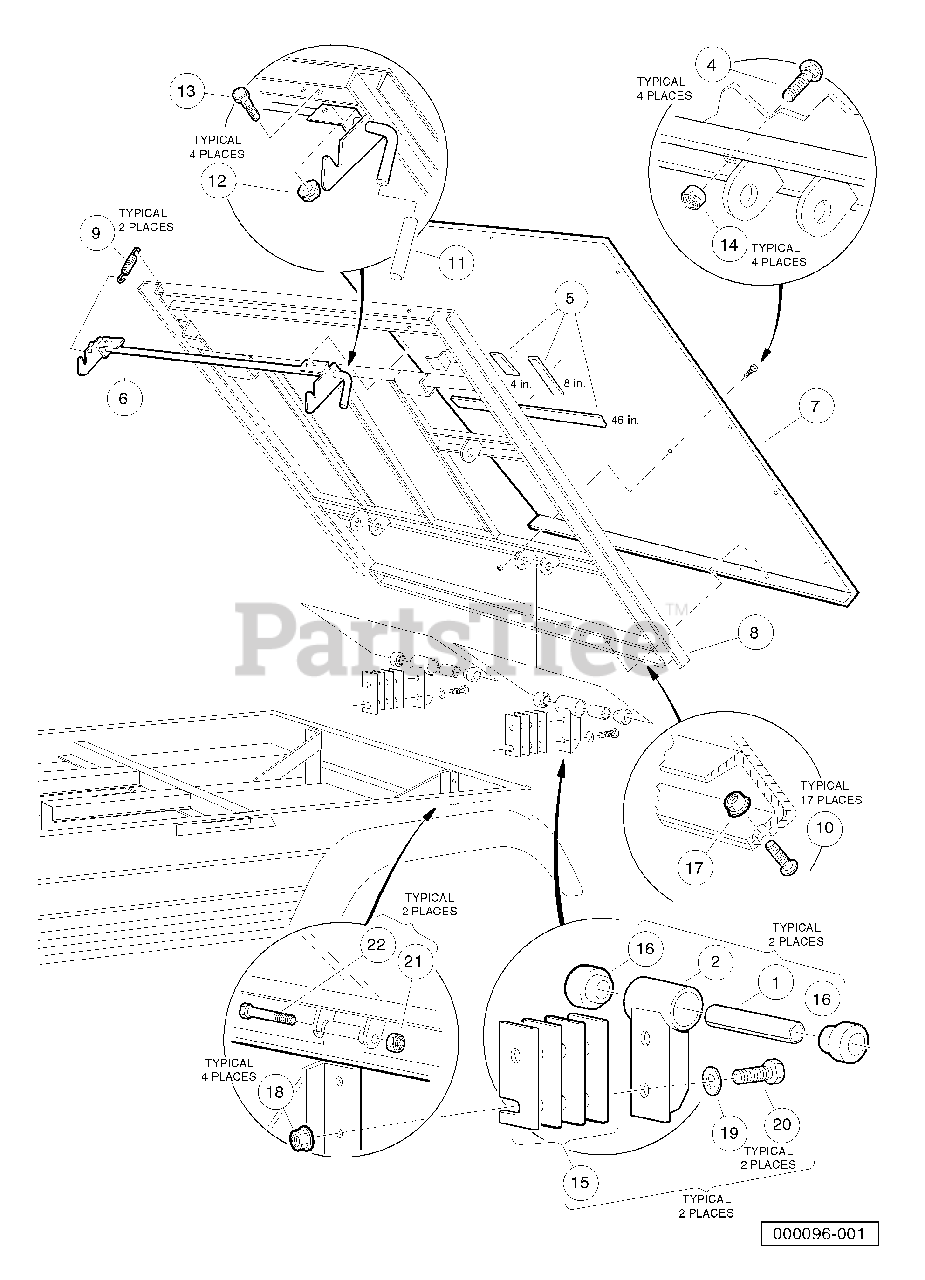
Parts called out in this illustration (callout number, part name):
1	Bushing, Steel
3	Assembly, Tilt Bed
4	Bolt, Carriage, 5/16-18 X 1.00
5	Tape, Vinyl Foam 1/8" x 3/4"
6	Latch Weld Assembly
7	Plate, Floor Bed
8	Frame Assembly
9	Extension, Spring Latch
10	Screw, 5/16-18 X 0.88 Torx Truss-Head
11	Grip, Tilt Latch Hand
12	Locknut, 1/4-20 Hex Whiz
13	Screw, 1/4-20 X 0.625 Hex-Head Cap
14	Locknut, 5/16-18 Nylon Insert
15	Shim, Tilt Bed Pivot
16	Bushing, Urethane
17	Locknut, 5/16-18 Hex Flange
18	Locknut, 3/8-16 Flanged Dimple
19	Washer, 3/8 Type B Hard Flat
20	Screw, Cap-hex Hd 3/8-16x1.25
21	Locknut, 3/8-16 Hex
22	Screw, 3/8-16 X 3.375 Hex Cap
